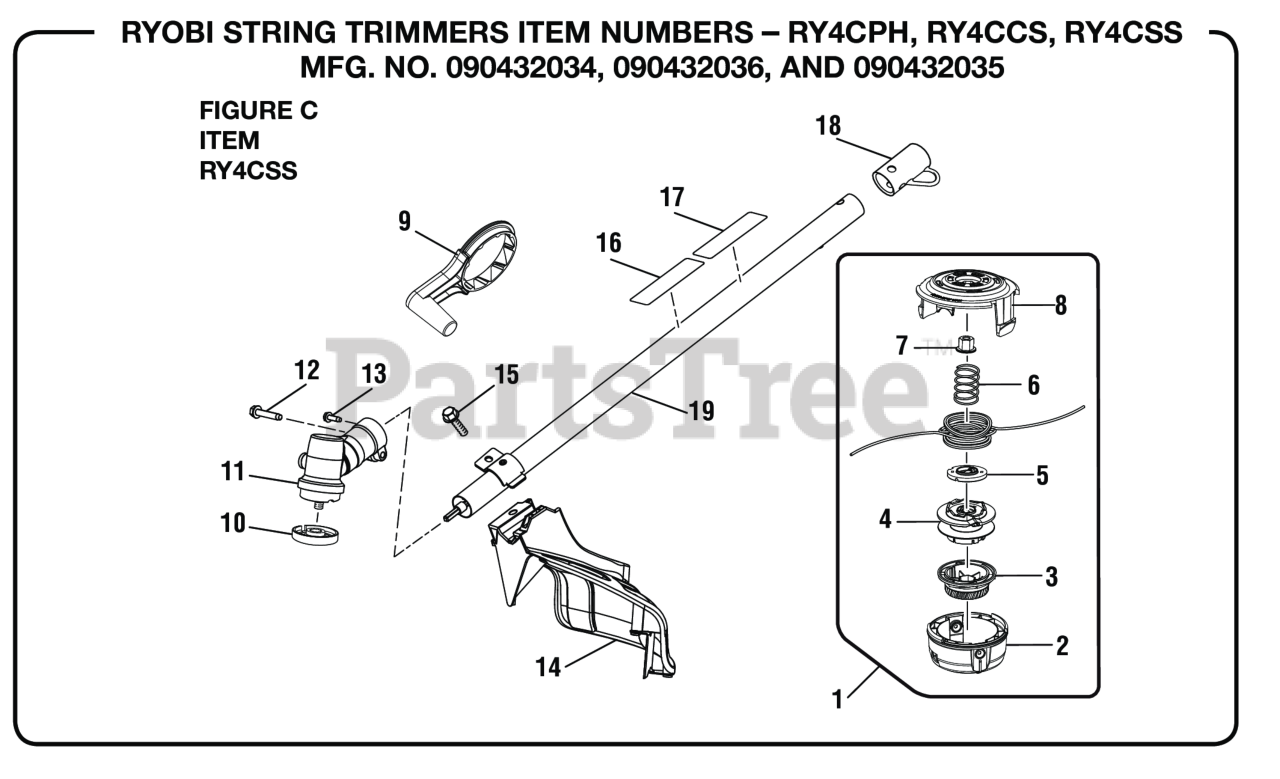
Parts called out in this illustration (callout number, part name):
1	Trimmer Head Assembly (.095)
2	Lower Housing
3	Bump Knob (Green)
4	Spool Assembly
5	String Guide
6	Compression Spring
7	Hex Nut (M8, Left Hand Threads)
8	Upper Housing
9	Crank Handle Assembly
10	FLANGED WASHER
11	Gear Case Assembly
12	Screw (1/4-20 x 1-1/4 in., Hex Washer Hd. S.T.)
13	Screw w/Washer (10-24 x 5/8 in., Hex Hd. T.F.)
14	Grass Deflector Assembly
15	SCREW (#1/4-20 X 1-1/4 in. HEX WASHER HD.)
16	Ryobi EXPAND-IT Label
17	Warning Icon Label
18	Storage Hanger Cap
19	Straight Shaft Assembly
